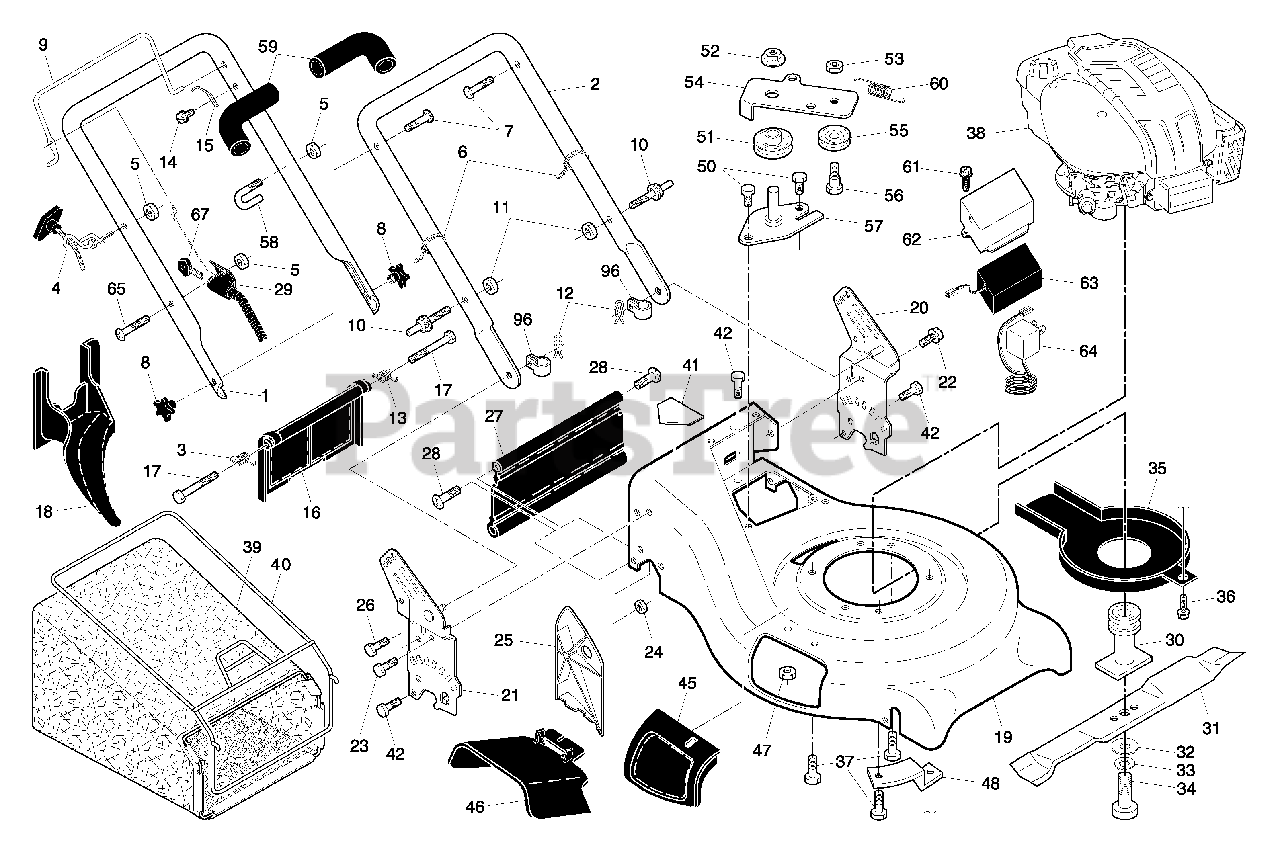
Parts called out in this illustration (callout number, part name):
1	Handle, Upper
2	Handle, Lower
3	Spring, Rear Door, RH
4	Guide, Rope, Side
5	Nut, Hex Lockwasher Insert 1/4-20
6	Wire, Tie
7	Bolt, Handle 5/16-18 x 1.75
8	Knob, Handle
9	Bail, Flat, Auto-Walk, Orange
10	Bolt, Carriage
11	Nut, Hex, Centerlock 5/16-18 UNC
12	Cotter, Hairpin
13	Spring, Rear Door, LH
15	Bracket, Upstop
16	Rear Door Assembly
17	Bolt, Rear Door
18	Plug, Mulcher
19	Kit, Housing
20	Handle Bracket Assembly, LH
21	Handle Bracket Assembly, RH
22	Screw, Hex Washer Head
23	Bolt, Hex Head 5/16-18 x 5/8
24	Nut, Hex, with Lock Washer Insert 5/16-18
25	Baffle, Side
26	Screw 12 x 5/8
27	Skirt, Rear
28	Screw, Hinge 1/4-20 x 1.25
29	Key Start Switch
30	Blade Adapter / Pulley
31	Blade, 21"
32	Washer, Hardened
33	Lockwasher, Helical Spring 3/8
34	Screw, Hex Head 3/8-24 x 1.38
35	Debris Shield
37	Bolt, Engine
40	Frame, Grassbag
41	Danger Decal
45	Mulcher Door Assembly
46	Defl ector, Discharge
48	Mounting Bracket, Debris Shield
51	Pulley Assembly, V-Groove
52	Flange Nut
53	Locknut
54	Idler Arm
55	Idler Pulley
56	Shoulder Bolt
57	Bracket Assembly
59	Grip, Handle, Foam, Smooth
60	Spring, Return
62	Box, Battery
63	Battery
64	Charger, Battery
96	Clip, Cable
